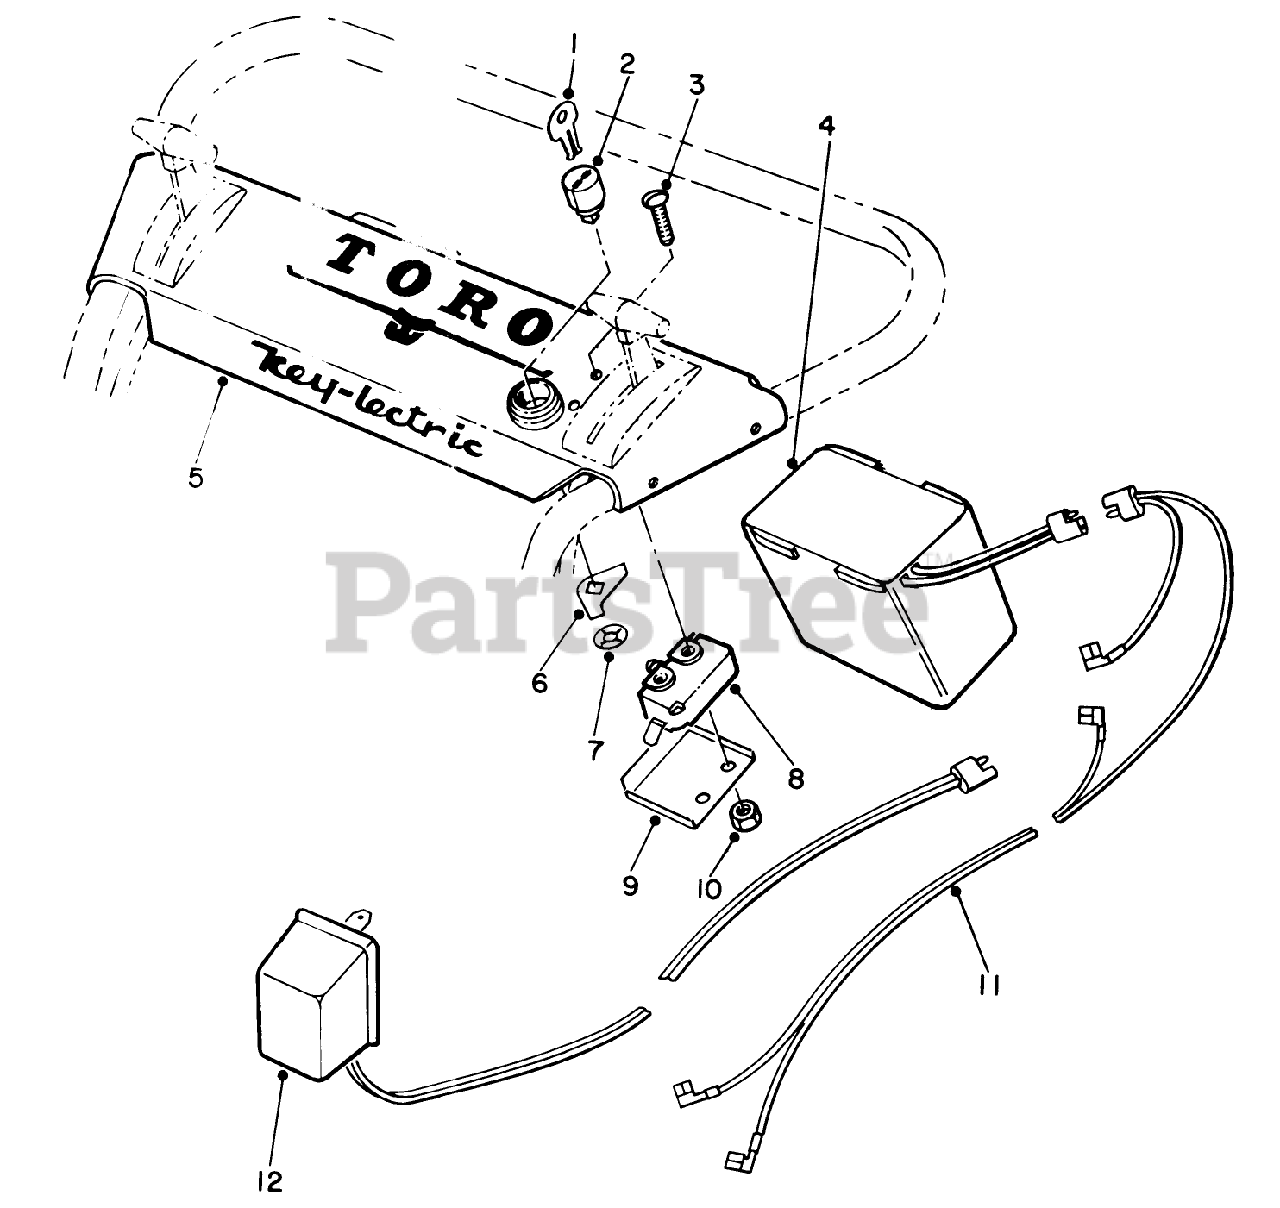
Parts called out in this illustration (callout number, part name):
2	Key Hsg.
4	Battery
5	Escutcheon Plate
8	Switch
9	Cover Switch
10	NUT-KEPS
11	Wire Harness
12	Charger
